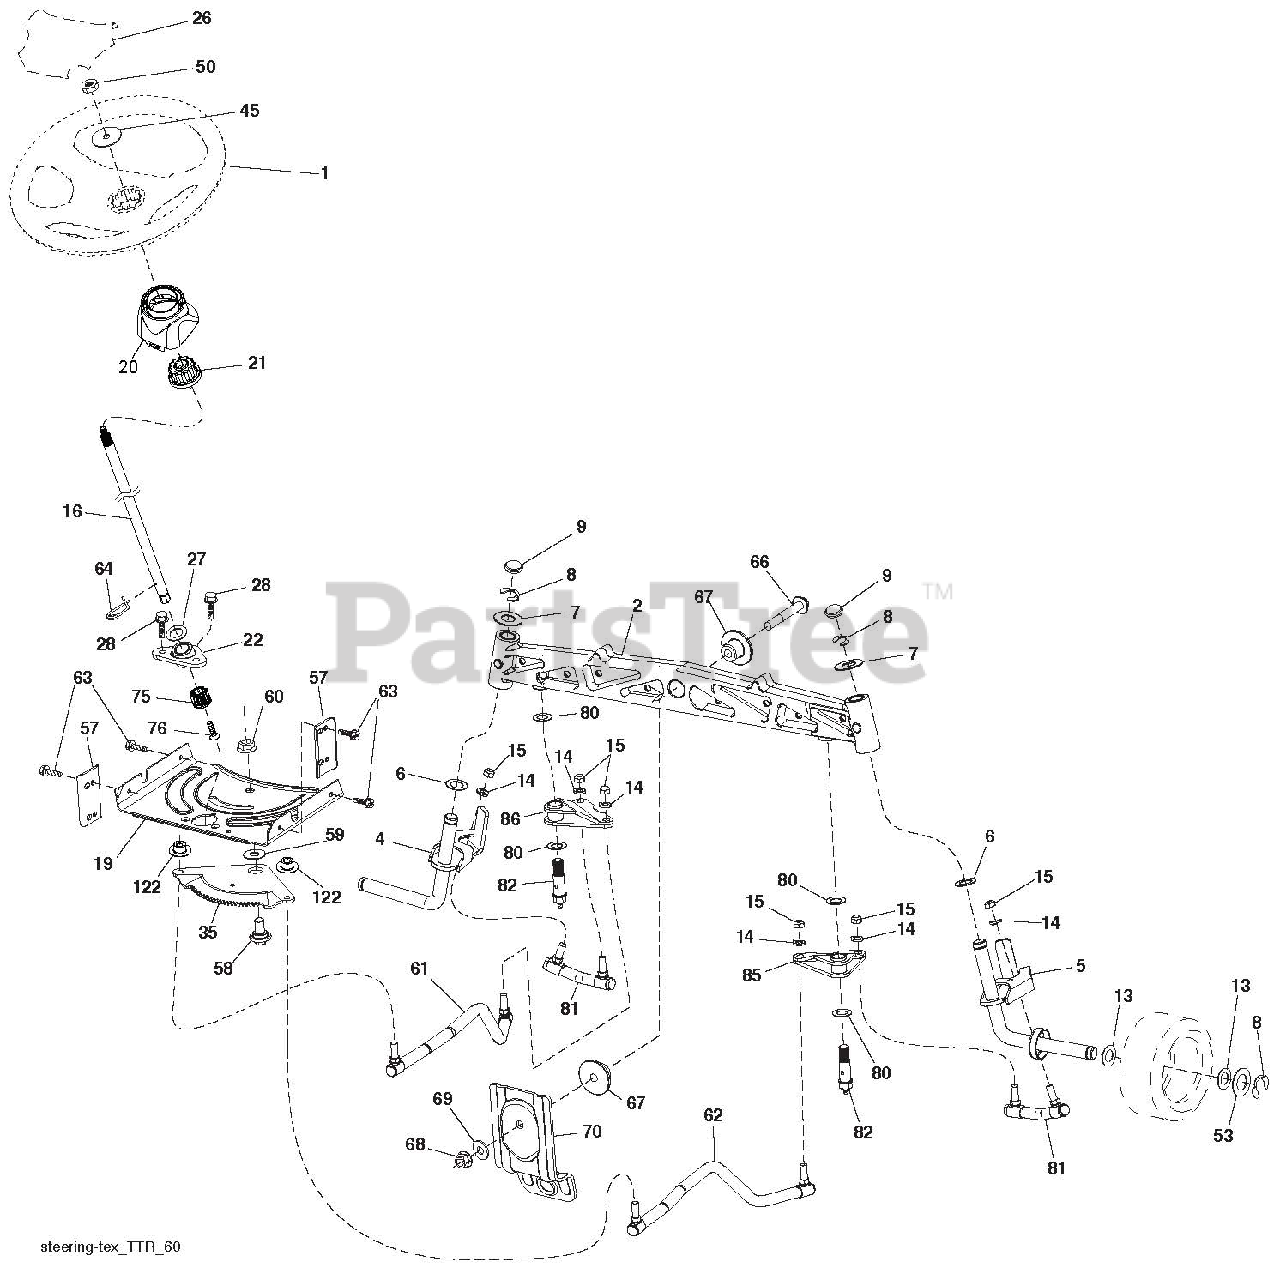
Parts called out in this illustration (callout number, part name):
1	WHEEL STEERING
4	SPINDLE LH
5	SPINDLE RH
6	WAHSER THRUST .75 X 1.230
7	WASHER.25/32 X 1-5/8 X 16GA.
8	RING.KLIP.#T5304-75
9	CAP.SPINDLE.FR.TOP.BLK.
13	WASHER.25/32 X 1 1/4 X 16 GA.
14	Washer, Lock 3/8
15	NUT.CROWNLOCK.3/8-24
16	SHAFT STEER
19	PLATE.STEER.DDL.NLT/NGT
20	BOOT.STEERING
21	ADAPTER.STEER
22	BEARING
26	CAP WHEEL STEERING HRS/SRS BLK
27	WASHER 21/32 X 1 X 1 GA.
28	SCREW.HEXWSH THDR3/8-16X3/4.BL
35	GEAR SECTOR
50	Nut, Hex, Flangelock 3/8-16
53	WASHER.HARDEN..793 X 1.637X060
57	BRACKET.UPSTOP.TEX
58	BOLT.SHOULDER.SECTOR.PIVOT.CFM
59	WASHER.THRUST.SECTOR.STEER.NLT
60	NUT.FLANGE LOCK.5/8-11
61	DRAG LINK LH
62	DRAG LINK RH
63	SCREW.5/16-18X3/4.SMGML.TAP/BL
64	RETAINER.CLIP.SPRING.STEERING
66	BOLT.HEX.FGHD.7/16-14 X 3.SERR
67	BUSHING.PM.FRONT AXLE
68	NUT.LOCK.FLANGE.7/16-14.GR5
69	WASHER.1.5 X .505 X .118
70	BRACKET
81	SUB ASM LINK
82	SUB ASM PIVOT BOLT
85	SUB ASM PIVOT RH
86	SUB ASM PIVOT LH
122	CAP GEAR SECTOR
